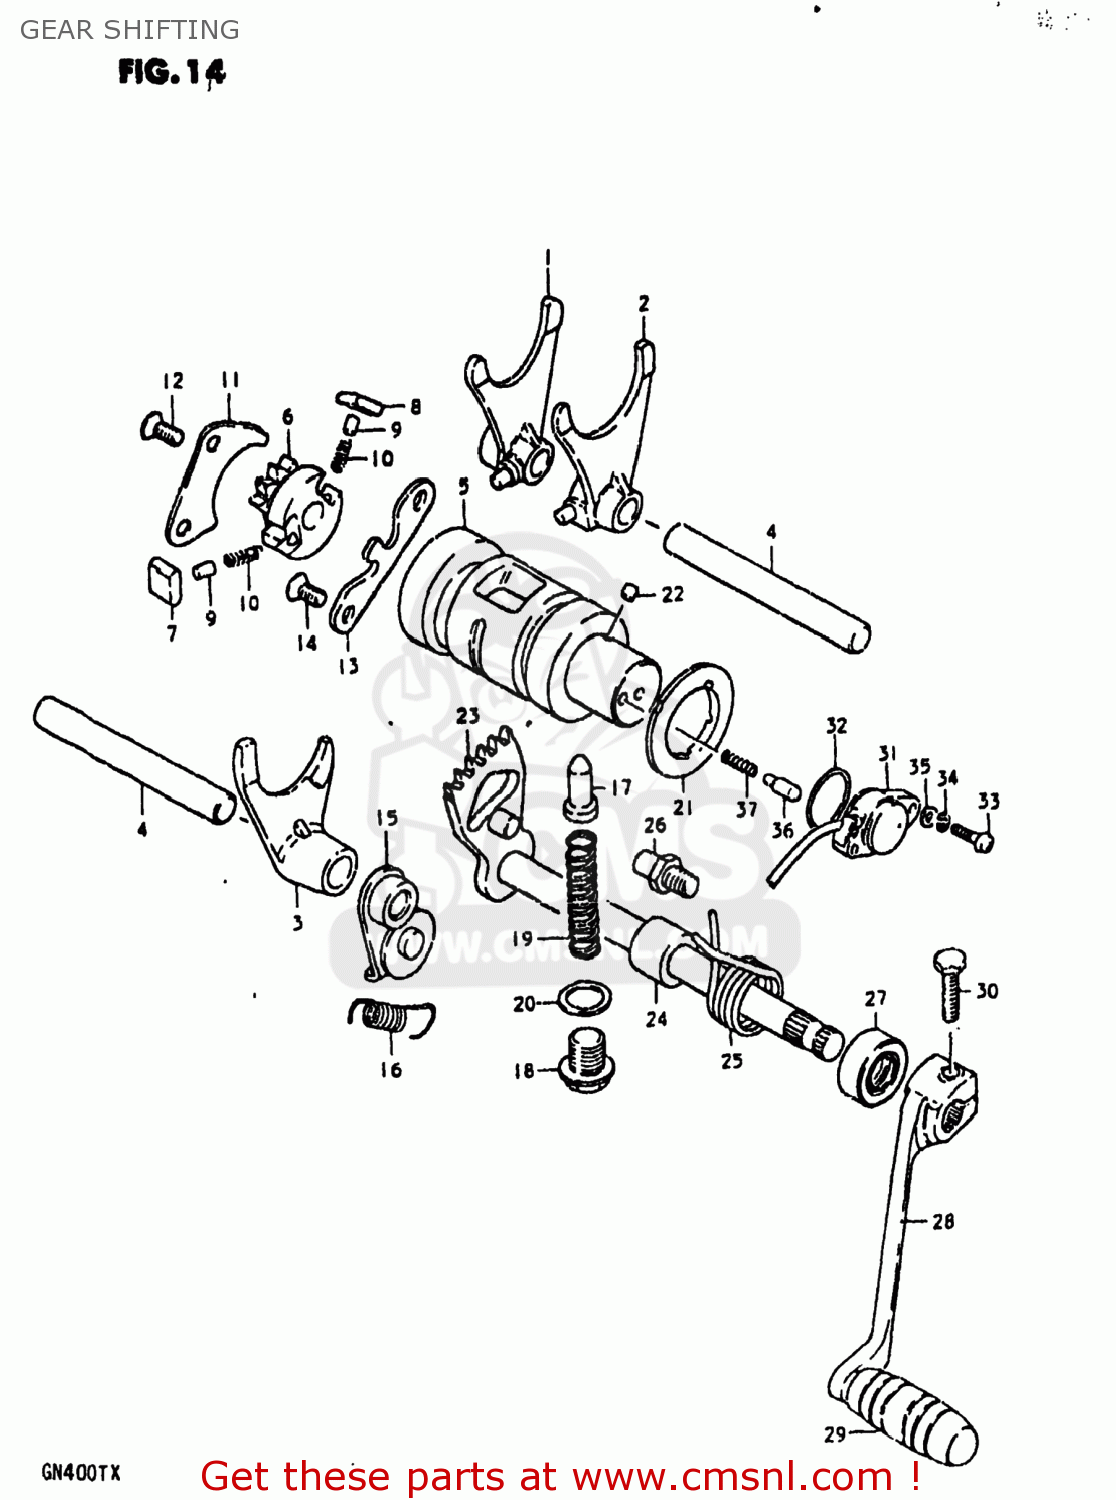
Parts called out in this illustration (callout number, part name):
1	FORK,GEAR SHIFT NO.1
2	FORK,GEAR SHIFT
3	FORK,GEAR SHIFT NO.3
4	SHAFT,GEAR SHIFT FORK
5	CAM,GEAR SHIFT
6	RETAINER,GEAR SHIFT CAM
7	PAWL,GEAR SHIFT NO.1
8	PAWL,GEAR SHIFT NO.2
9	PIN(5X8)
10	SPRING
11	LIFTER,GEAR SHIFT PAWL
12	SCREW
13	GUIDE,GEAR SHIFT CAM
14	SCREW
15	STOPPER,GEAR SHIFT CAM
16	SPRING
17	STOPPER,GEAR SHIFT CAM NO.2
18	PLUG
19	SPRING
20	GASKET(14X19.2X2) (NAS)
21	PLATE,GEAR SHIFT CAM STOPPER
22	PIN 4X6
23	SHAFT,GEAR SHIFT
24	SPACER(12X20X15.3)
25	SPRING
26	STOPPER,GEAR SHIFT CAM
27	OIL SEAL
28	LEVER ASSEMBLY,GEAR SHIFTING
29	RUBBER,GEAR SHIFT PEDAL
30	BOLT
31	TERMINAL BASE ASSY,GEAR SHIFT
32	O-RING (D:2.4 ID:26.2)
33	SCREW 5X20
34	LOCK WASHER
35	WASHER
36	PIN(5X15.5)
37	SPRING
